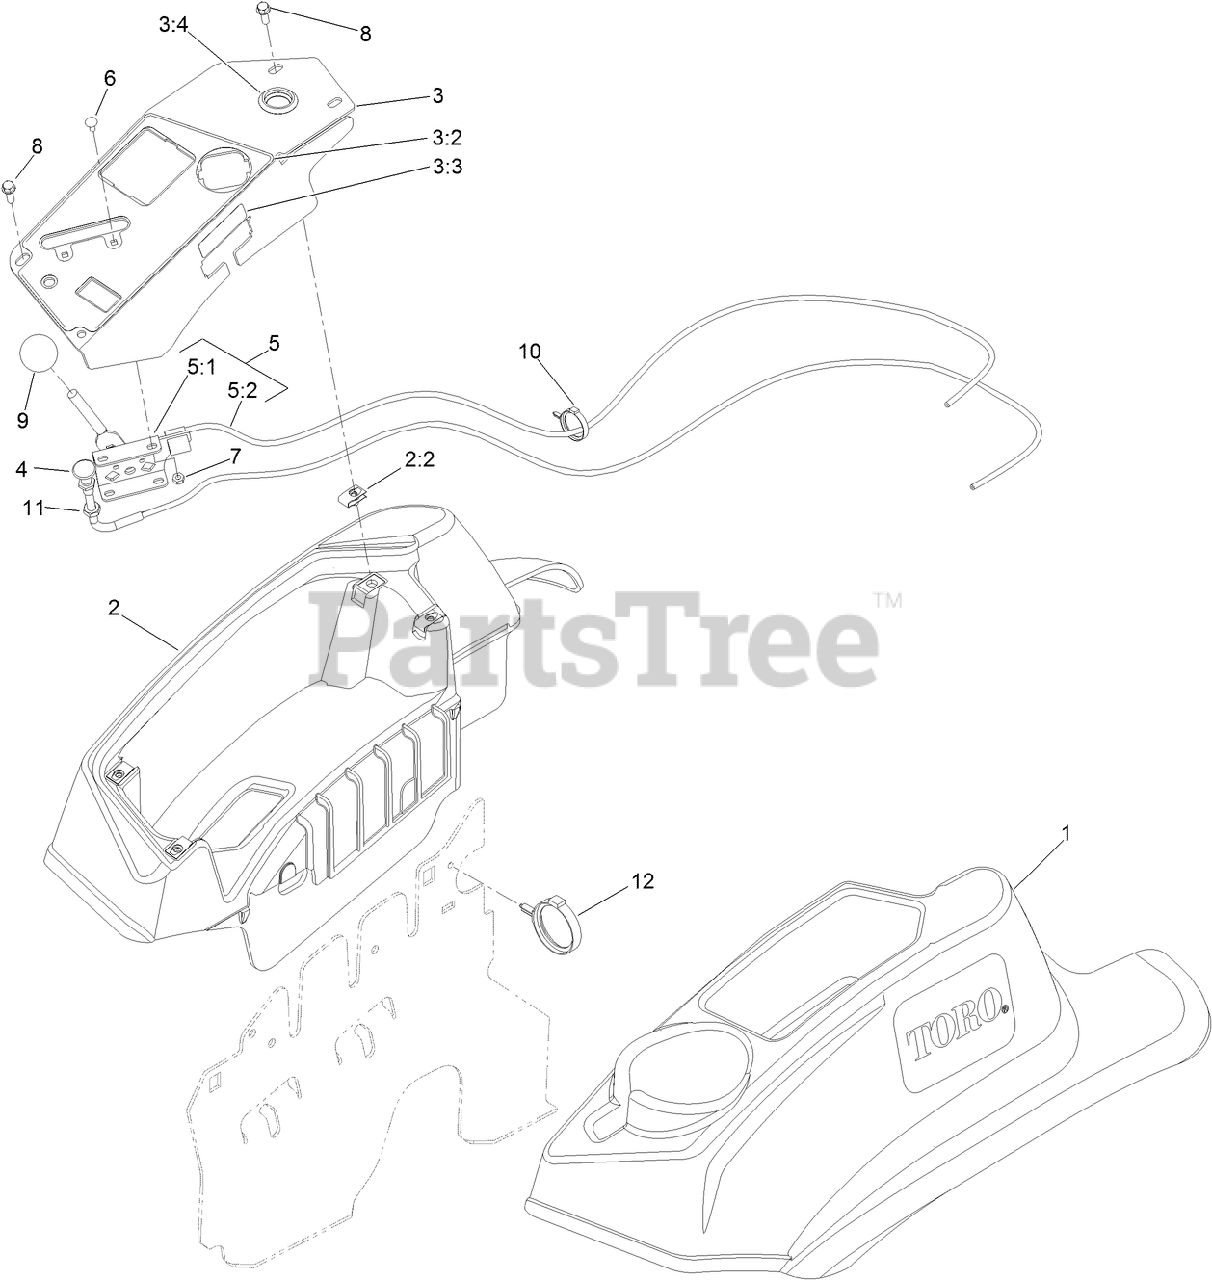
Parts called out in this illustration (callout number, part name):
1	CONSOLE-LH
2	RH CONSOLE ASM
3	CONTROL PANEL ASM
3:2	DECAL-PANEL, CONTROL
3:3	DECAL-FUSES
3:4	PLUG-PLASTIC
4	CONTROL-CHOKE
5	THROTTLE CONTROL ASM
5:1	LEVER-THROTTLE
6	BOLT-CARR
7	NUT-LOCK, NI
8	SCREW-HWH
9	KNOB-BALL
10	CLAMP-HOSE
11	NUT-HJ
12	CLAMP-HARNESS
